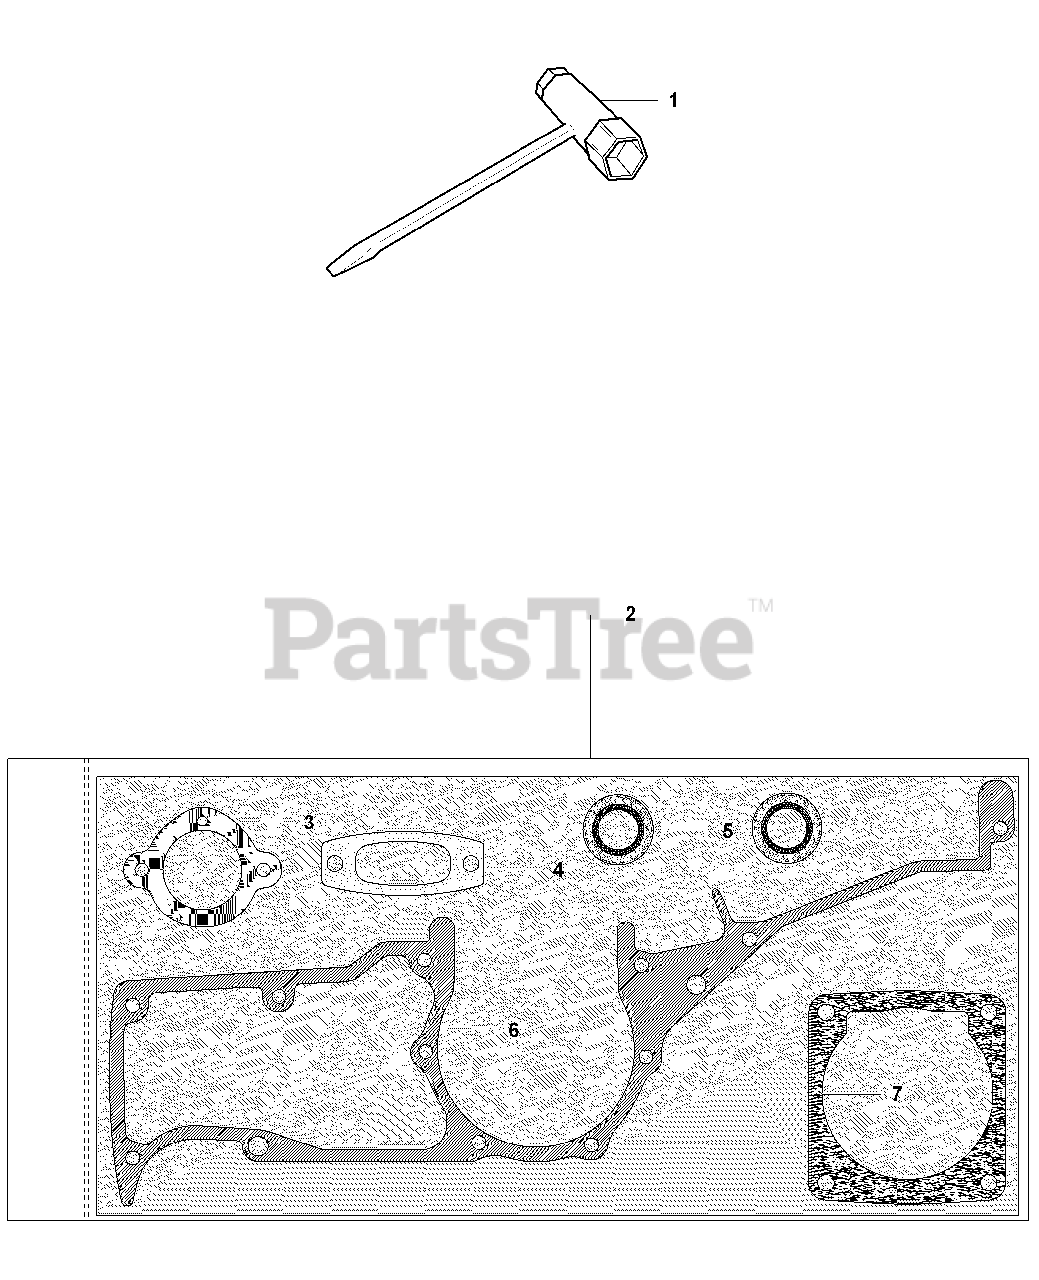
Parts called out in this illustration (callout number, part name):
1	COMBINATION TOOL
2	GASKET KIT
3	GASKET
4	GASKET MUFFLER
5	SEALING RING
6	CRANKCASE GASKET
